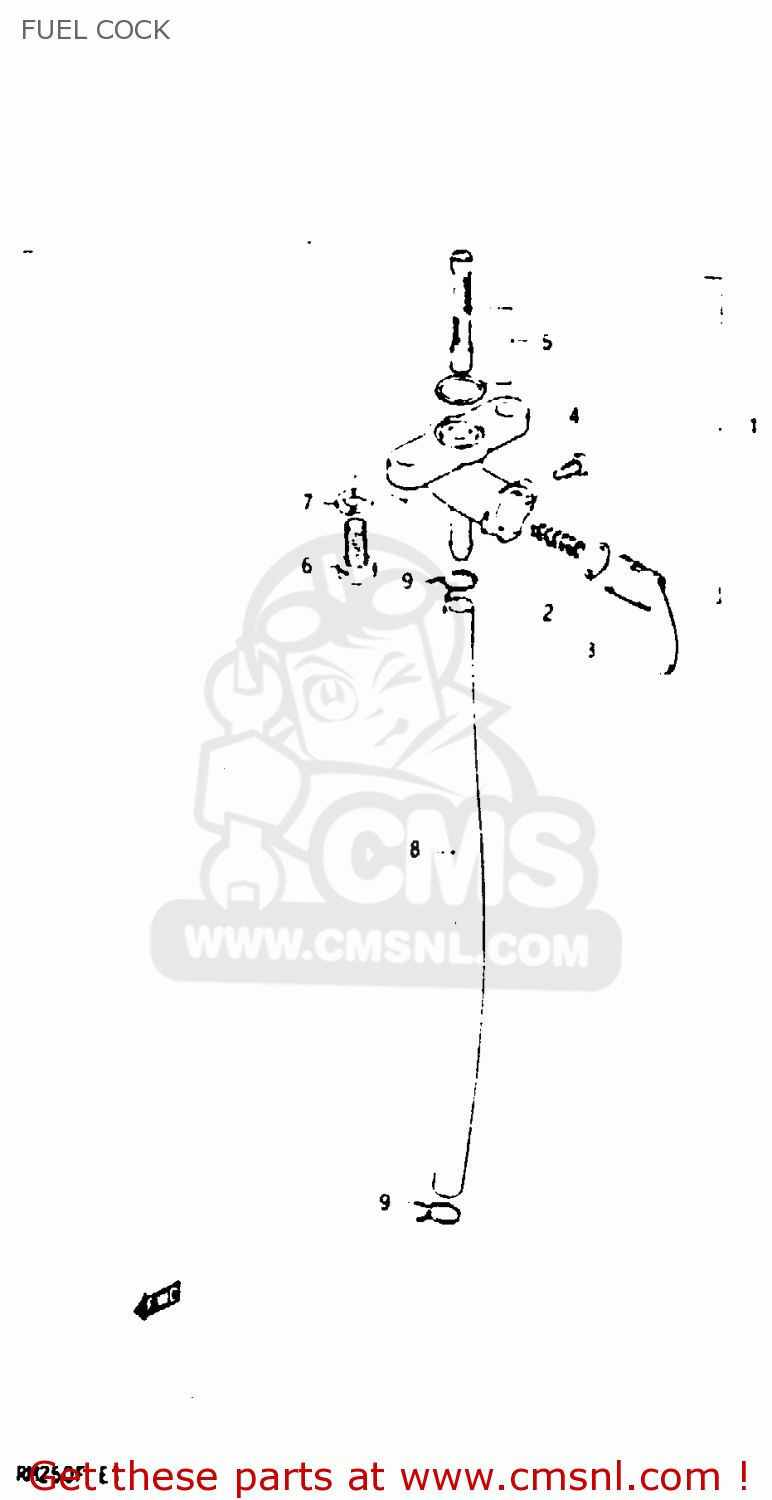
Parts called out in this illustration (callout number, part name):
1	COCK ASSY,FUEL
2	SPRING,FUEL COCK VALUE
3	O RING,LEVER
4	SCREW
5	FILTER SET FUEL
6	SCREW
7	LOCK WASHER
8	HOSE,FUEL
9	CLAMP
